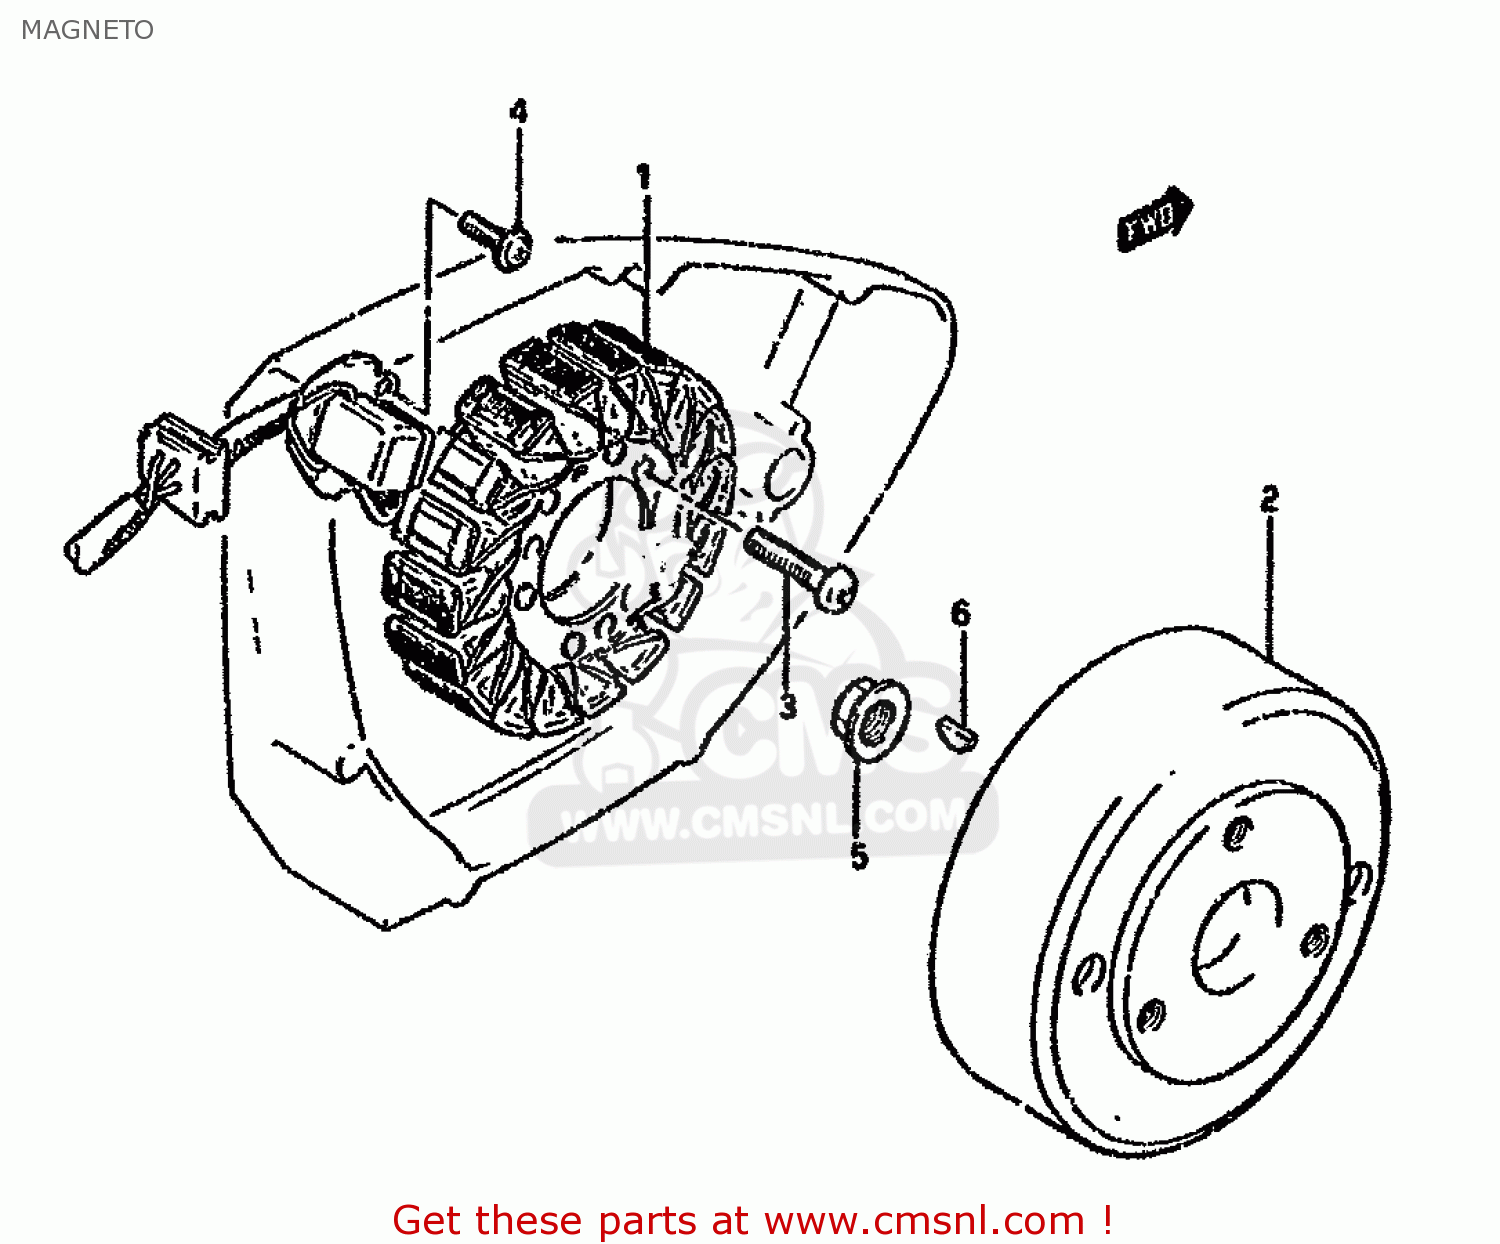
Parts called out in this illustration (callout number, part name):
1	STARTER ASSY
2	ROTOR,FLYWHEEL
3	SCREW
4	SCREW
5	NUT
6	KEY
